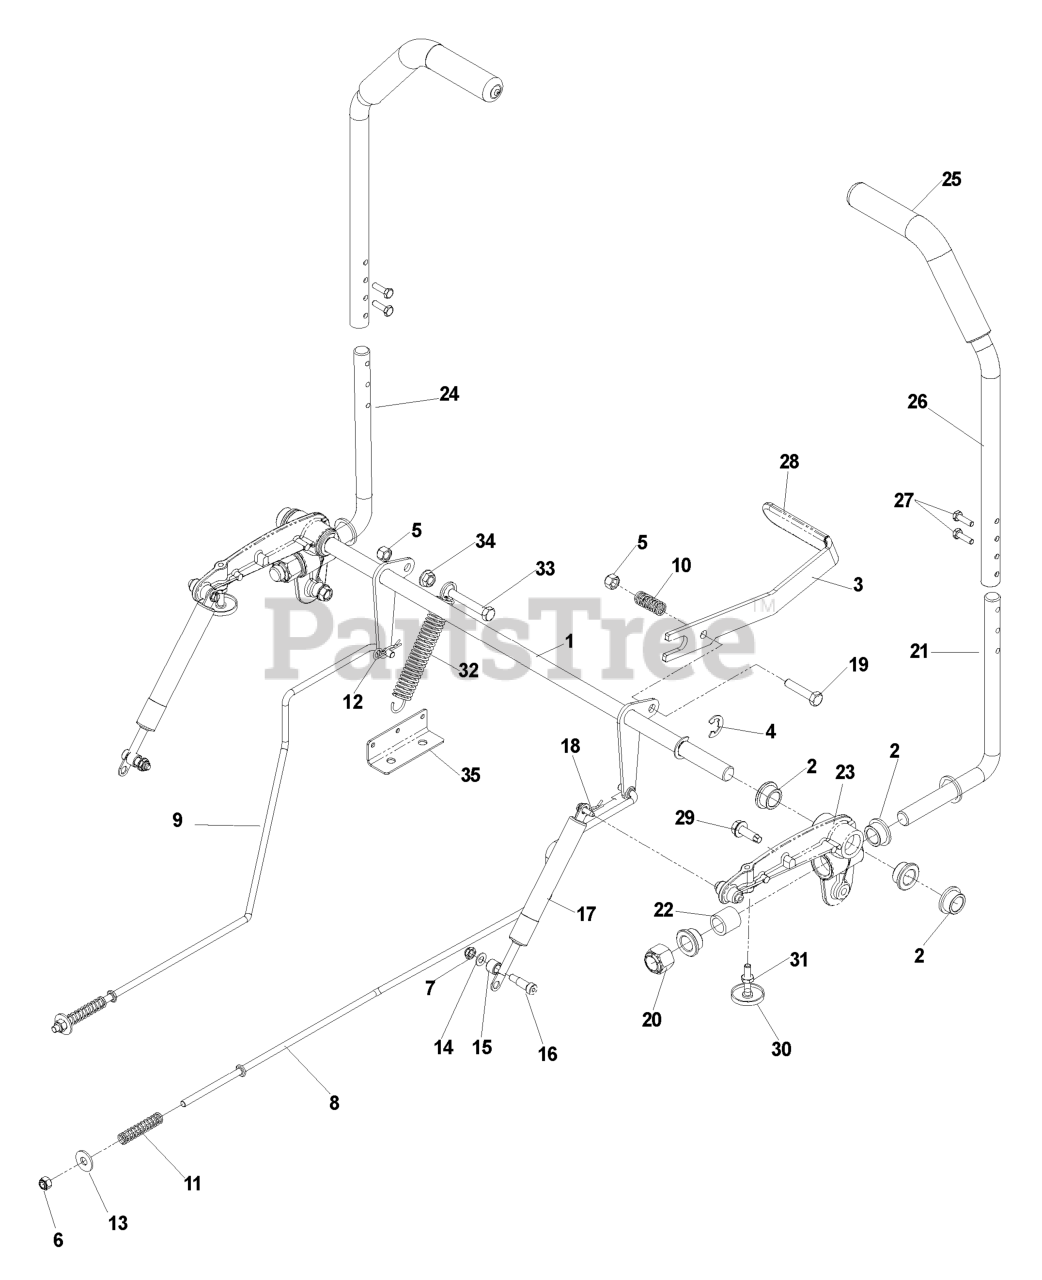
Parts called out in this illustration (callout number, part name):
1	SHAFT, MOTION, BRAKE PLATED
2	MOTION BUSHING
3	BRAKE LEVER
4	E-RING 5/8
5	NUT 5/16 NYLOC
6	NUT.1/4-20.HEX.NYLOC.ZD
7	JAM NUT 1/4C (2 2 PW01)
8	BRAKE ROD FORMED RT
9	BRAKE ROD FORMED LT
10	BRAKE LEVER SPRING
12	HAIRPIN #2
13	WASHER 5/16 FLAT
16	SCREW, 5/16 X 5/8 SHOULDER
18	SCREW #10 X 1/2 SELF TAPPING
19	CAPSCREW 5/16 X 1/1/2 HEX HEAD
20	NUT 5/8-11 NYLOC
21	MOTION CONTROL ARM, WLDMNT RH
22	BUSHING ELASTOMER
23	MOTION CASTING
24	MOTION CONTROL ARM, WLDMNT LH
25	CONTROL LEVER CUSHION
26	CONTROL LEVER
27	HCS 1/4-20X7/8 GR5
28	BRAKE LEVER CAP
29	BOLT 5/16-18 X 1 1/4 TFS
30	POST, RETURN TO NEUTRAL
31	NUT 1/4-20 JAM
32	SPRING-TRANS
33	HCS 5/16-18X2
34	NUT 5/16C WHIZ
35	SPRING BRACKET
